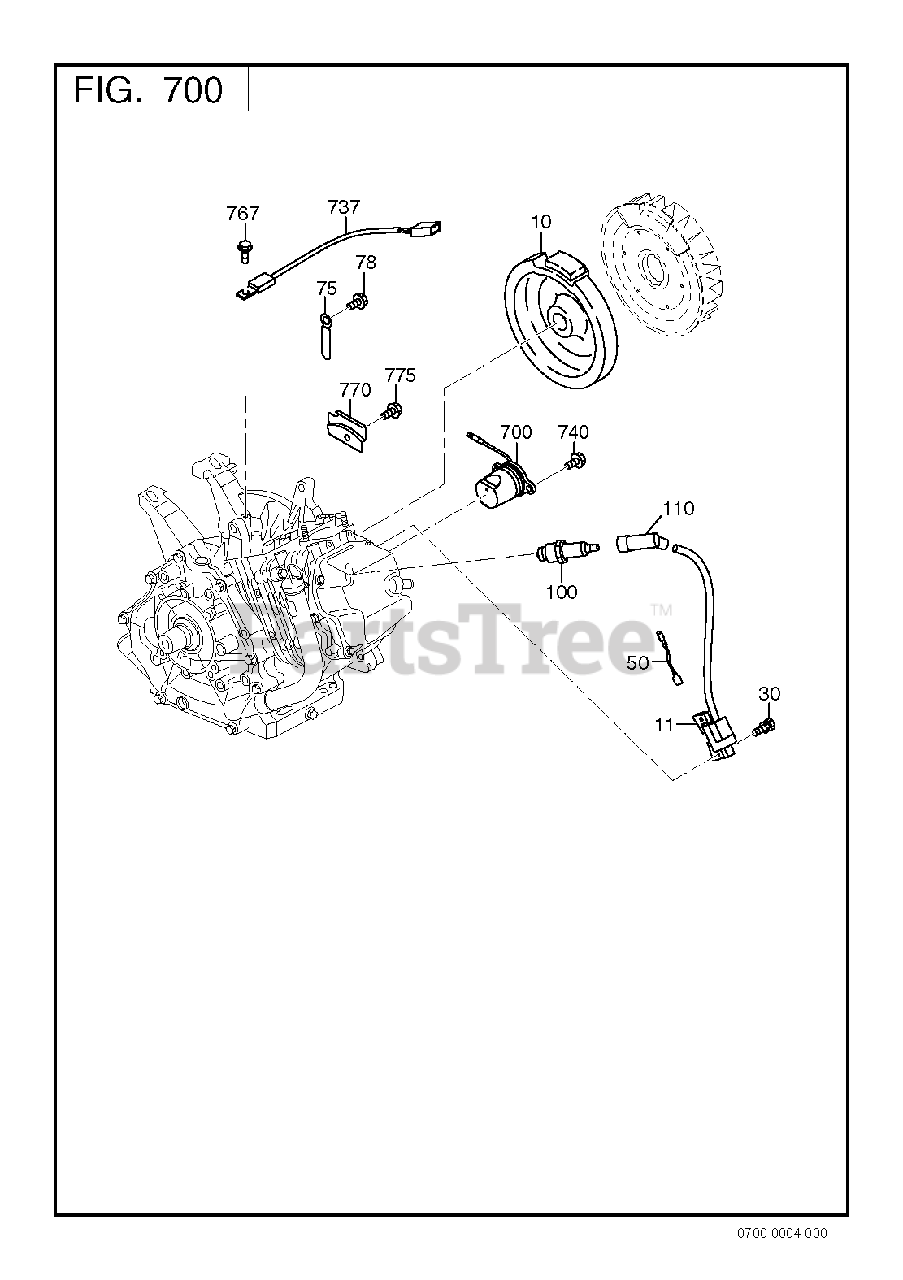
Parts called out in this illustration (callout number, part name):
11	IGNITION COIL CP
30	BOLT AND WASHER AY
110	SPARK PLUG CAP
737	SENSOR CP (TEMP)
